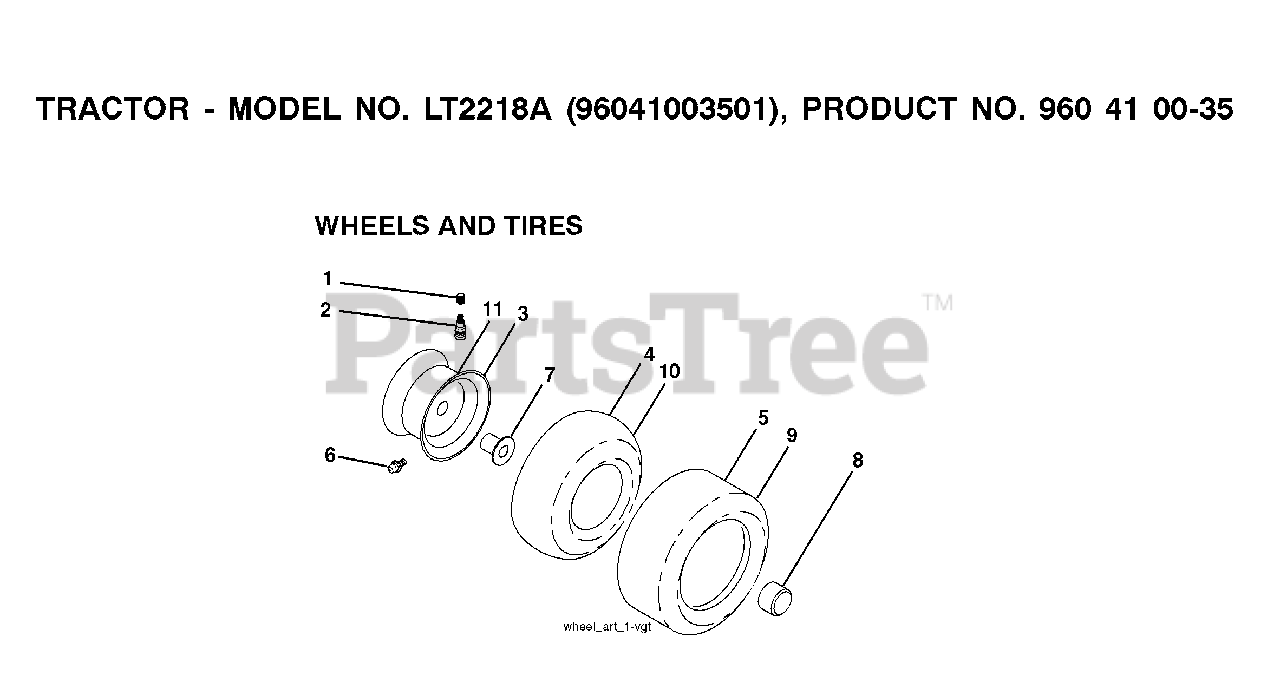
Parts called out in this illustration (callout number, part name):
1	VALVE CAP
2	VALVE STEM LT
3	RIM ASM 6" FRONT SILVER
4	TUBE.5.3/4.5/6
5	TIRE HEAVY DUTY
6	FITTING LT
7	BEARING T
8	CAP, AXLE BLK
9	TIRE.TS.20X10-8
10	TUBE
11	RIM ASM 8" REAR SILVER
